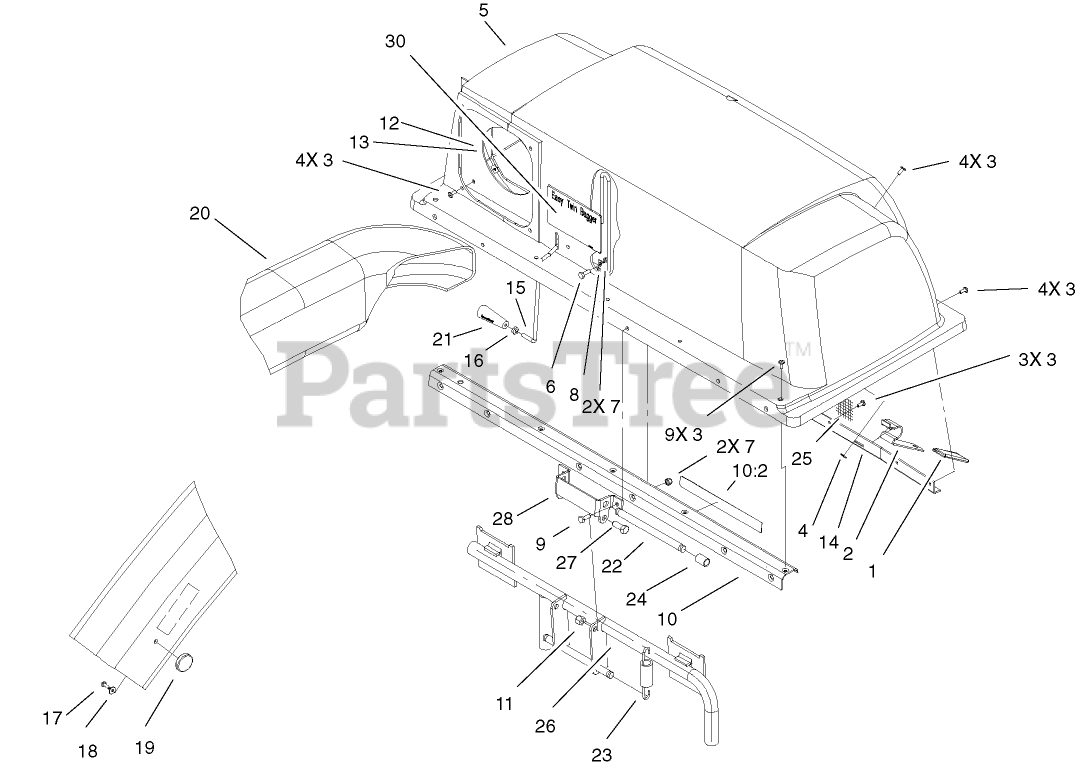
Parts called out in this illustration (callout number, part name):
2	LATCH-BAGGER, TOP
3	RIVET-BLIND
4	WASHER-FLAT
5	TOP-BAGGER
6	SCREW-HH
7	NUT-LOCK, NI
8	CLAMP
9	SCREW-HH
10	STIFFENER ASM
10:2	DECAL-CAUTION
11	NUT-LOCK, NI
12	CLAMP-SEAL
13	SEAL-CHUTE
14	SUPPORT-SCREEN
15	FEELER-FILL, BAG
16	NUT-JAM
17	SCREW-PPHTF
18	WASHER-PLAIN
20	CHUTE-DISCHARGE
21	HANDLE-TAPERED
22	PIN-SPRING
23	SPRING-EXTENSION
24	SPACER
25	SCREEN-BAGGER
26	FRAME ASM
27	SCREW-HH
28	HINGE-BAG, TOP
30	DECAL
